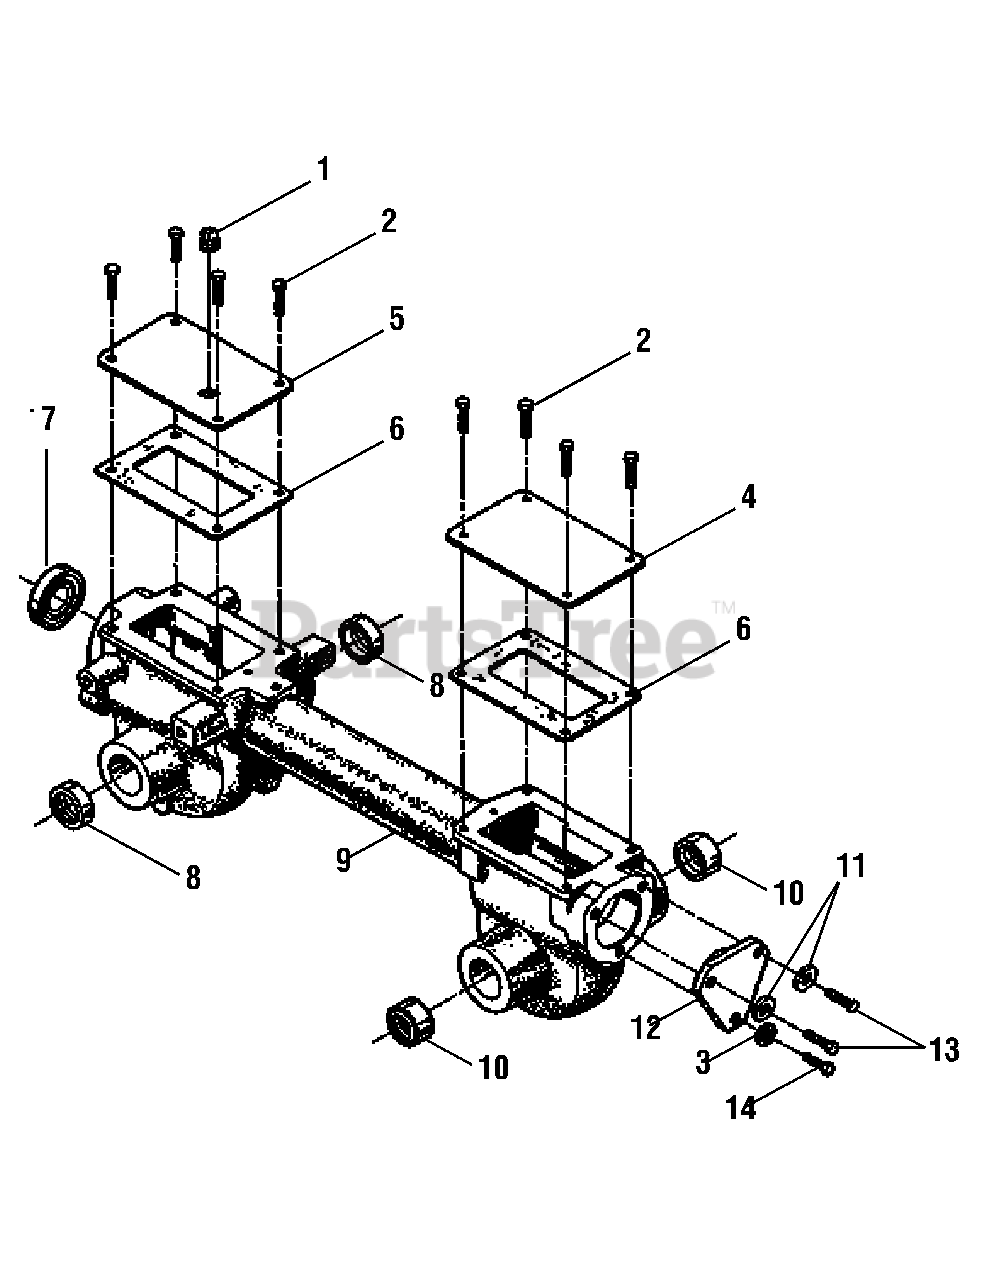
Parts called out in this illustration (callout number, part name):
1	Plug, Transmission Oil Fill
2	Hex Hd. Flange Screw, 5/16-18 x 5/8,Gr. 5
3	Lock Washer, 5/16
4	Rear Cover, Transmission
5	Front Cover, Transmission
6	Gasket, Housing Cover
7	Oil Seal, Drive Shaft
8	Oil Seal, Wheel Shaft
9	Transmission Housing Assembly
10	Oil Seal, Tine Shaft
11	Washer, Flat, .344 x .750 x .120
12	Rear Bearing Cap
13	Hex Hd. Flange Screw, 5/16-18 x 1
14	Hex Hd. Flange Screw, 5/16-18 x 3/4
